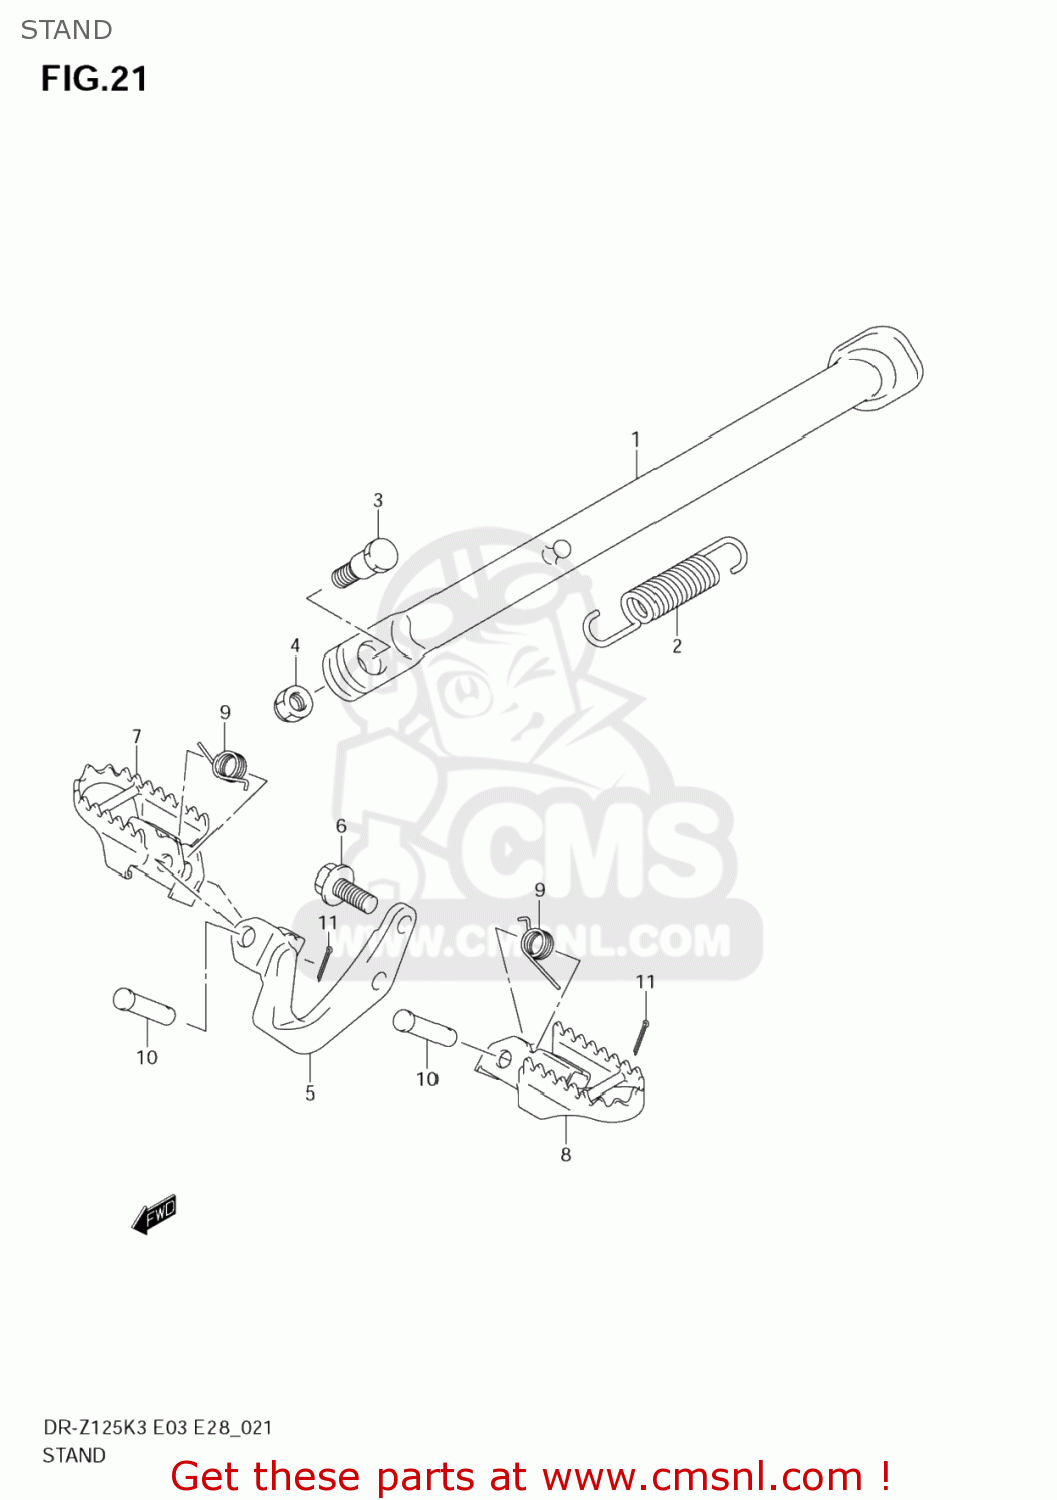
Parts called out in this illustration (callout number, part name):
1	STAND,PROP
2	SPRING
3	BOLT(10X33)
4	NUT,PROP STAND
5	BRACKET,FR FOOTREST,R
6	BOLT
7	FOOTREST,FRONT,RIGHT
8	FOOTREST,FRONT,LEFT
9	SPRING
10	PIN
11	PIN
